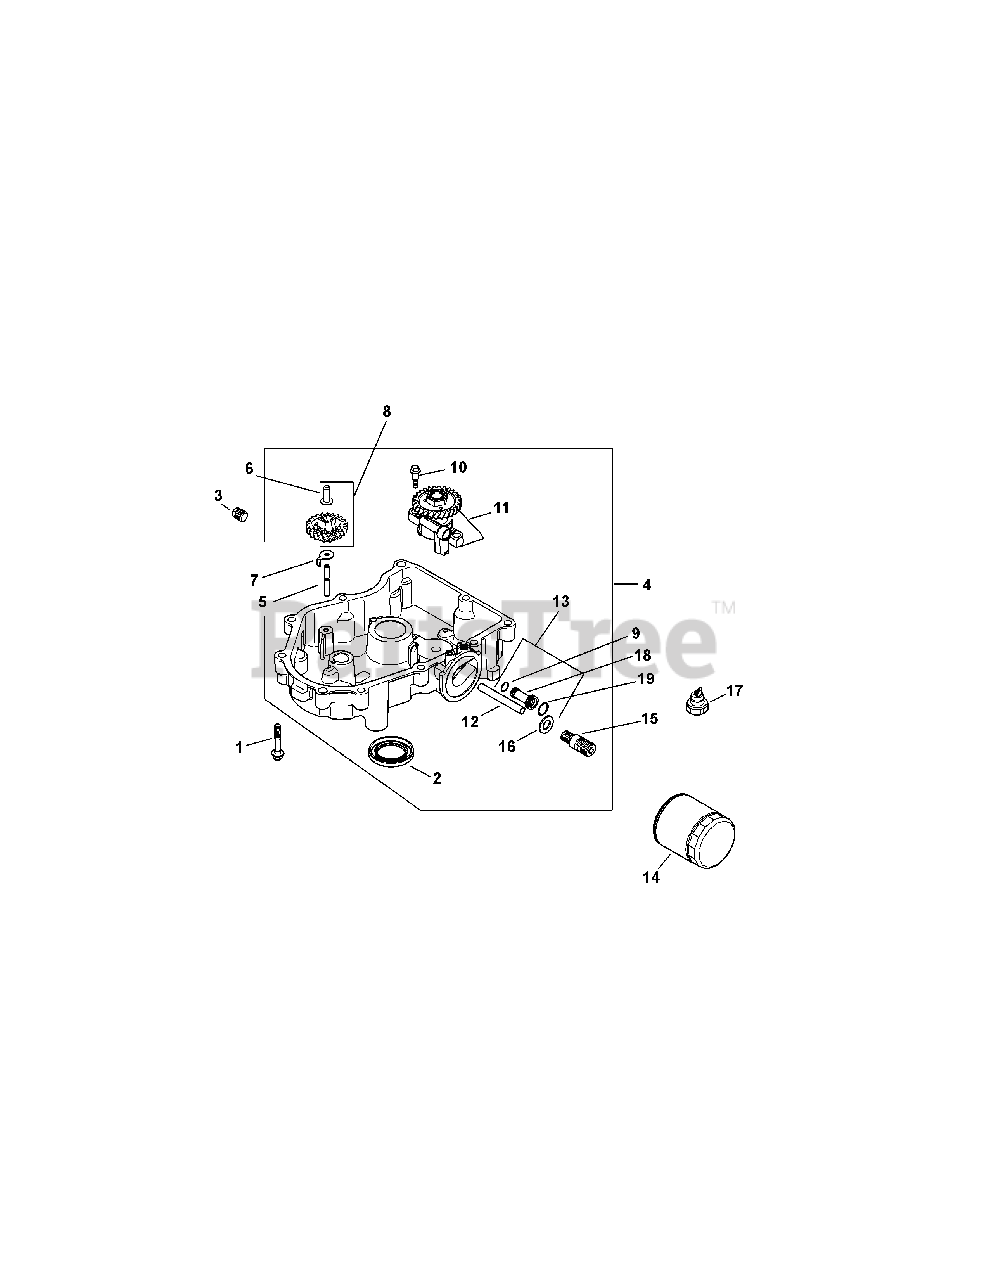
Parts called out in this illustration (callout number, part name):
1	Flange Screw, M8 x 1.25 x 45
2	Oil Seal, 2.38 x 1.45
3	Square Head Pipe Plug, 3/8
4	Oil Pan Assembly
5	Governor Gear Shaft
6	Governor Regulating Pin
8	Governor Gear Kit
9	Oil Pick-Up O-Ring
11	Oil Pump Assembly
12	Oil Feed Tube (Filter to Oil Pan)
13	Oil Feed Tube Assembly
15	Oil Filter Nipple
17	Oil Pressure Switch
18	Oil Feed Tube
